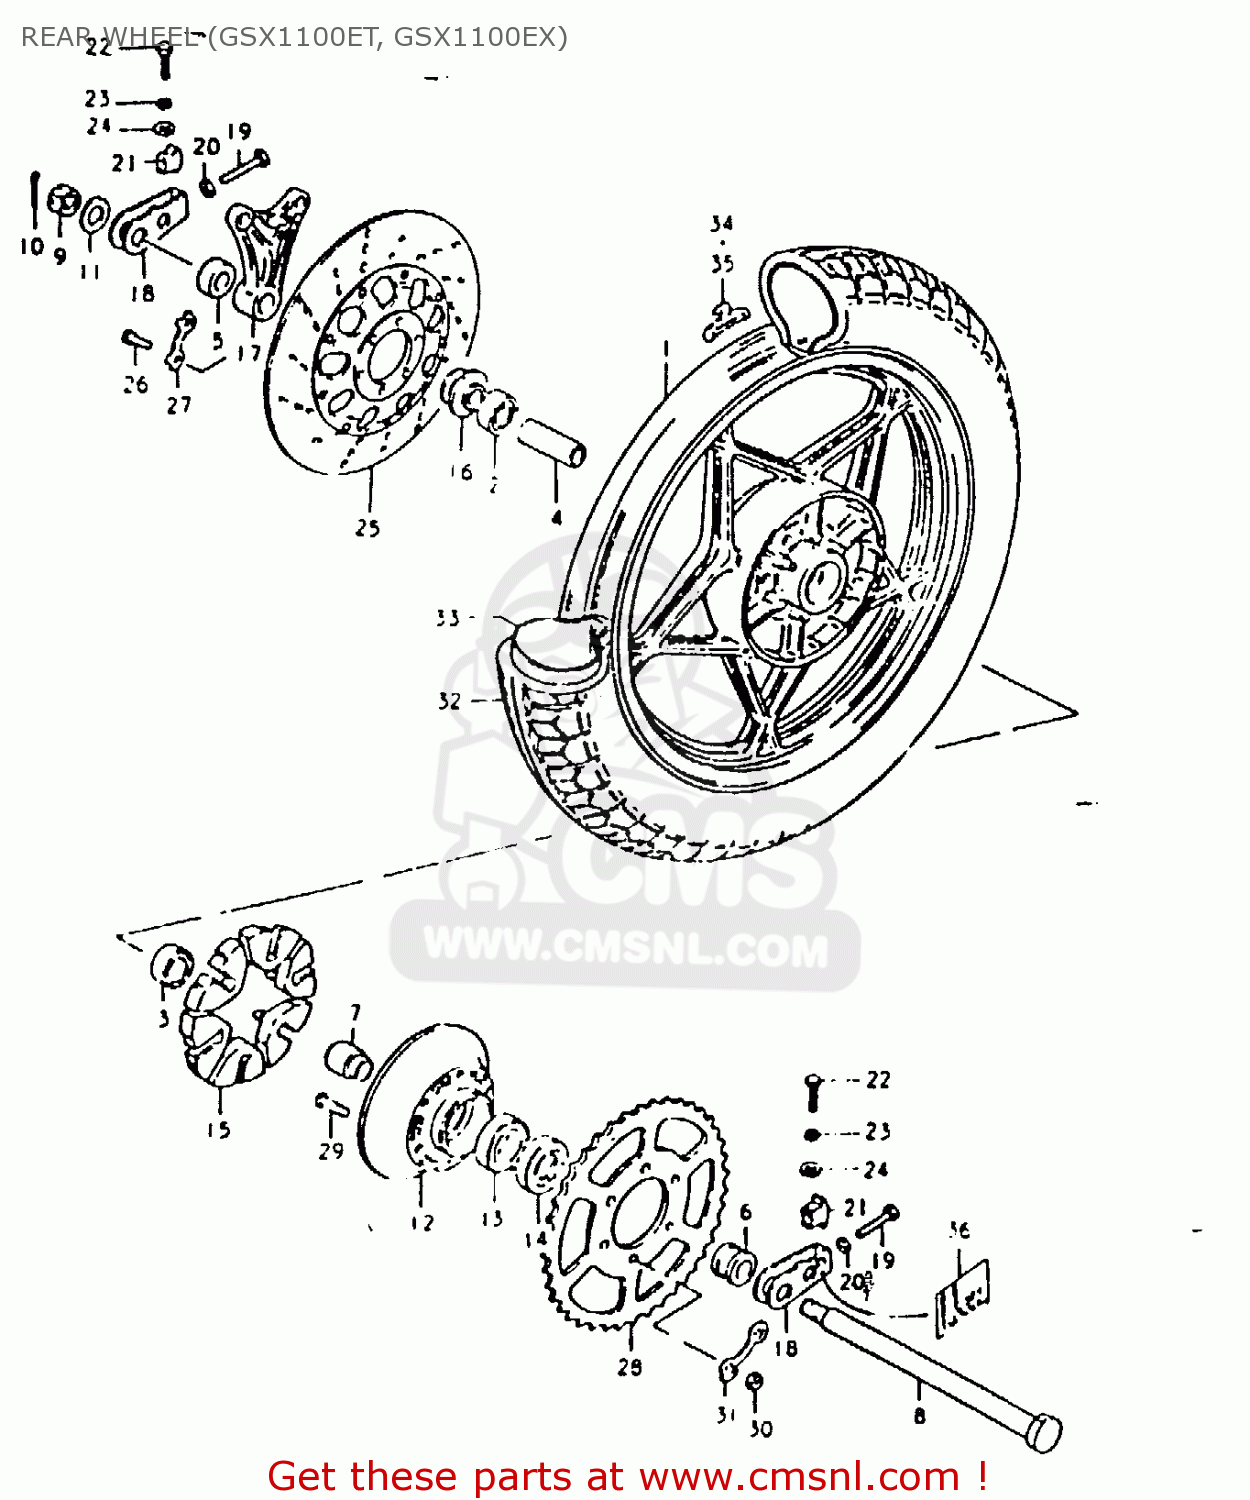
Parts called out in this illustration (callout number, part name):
1	WHEEL,REAR
2	BEARING WHEEL REAR(20X47X14)
3	BEARING, LH
4	SPACER(20.5X28X88)
5	SPACER(20X38X12)
6	SPACER(20X33X28.3)
7	SPACER,REAR HUB BEARING
8	AXLE,REAR
9	NUT 18MM
10	PIN,COTTER
11	WASHER(19X34X4)
12	DRUM,REAR SPROCKET MOUNT
13	BEARING
14	SEAL,OIL(33X62X7)
15	ABSORBER,REAR HUB SHOCK
16	SPACER,REAR AXLE
17	BRACKET,RR,CALIPER
18	ADJUSTER,CHAIN
19	BOLT
20	NUT
21	SUPPORTER,CHAIN ADJUST
22	BOLT
23	LOCK WASHER
24	WASHER
25	DISC,RR BRAKE
26	BOLT(8X30)
27	WASHER
28	SPROCKET,REAR
29	BOLT
30	NUT
31	WASHER
32	TIRE 4.50V17
33	TUBE ASSEMBLY,WHEEL,INNER
34	BALANCER,WHEEL
35	BALANCER,WHEEL
36	LABEL,CHAIN WEAR INDICATOR
